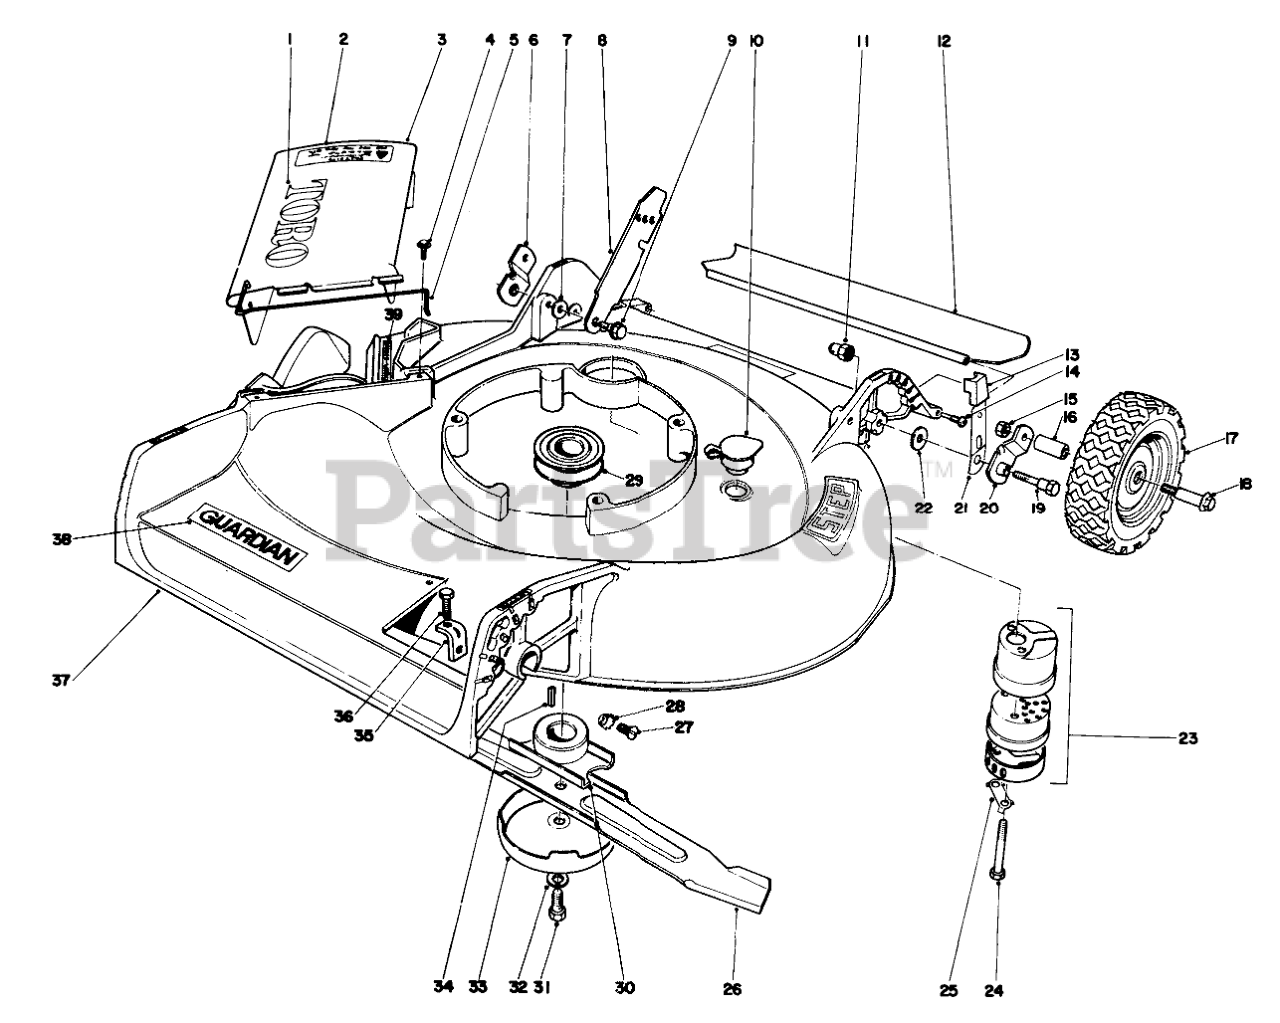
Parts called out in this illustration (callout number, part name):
1	Decal
2	Caution Decal
3	Deflector Assembly (Incl. Ref. #1, 2 & 5)
4	SCREW
5	SPRING HINGE
6	Pivot Arm
7	SPACER
8	Latch
9	SCREW-SHOULDER
10	Plug Washout
11	HANDLE PIVOT NUT
12	Rear Shield
13	Knob Arm
14	SAFTEY SHIELD SCREW
15	Nut
16	Bushing
17	Wheel & Tire (Incl. Ref. #16)
19	5/16-18 PIVOT SCREW
20	Pivot Arm
21	SPRING ARM ASM
22	Washer
23	Muffler Assy. (Incl. Ref. #24 & 25)
24	SCREW-HH
25	CLIP - LOCKING
26	Blade
27	5/16-18X5/8 FLT HD MS
28	Lockwasher
29	DRIVER PULLEY
30	Blade Retailer
31	SPECIAL SCREW
32	WASHER-LOCK
33	AntiScalp Cup
34	Key Square
35	ADJ BRACKET
36	SCREW-HH
37	Housing
38	Decal
39	Decal
